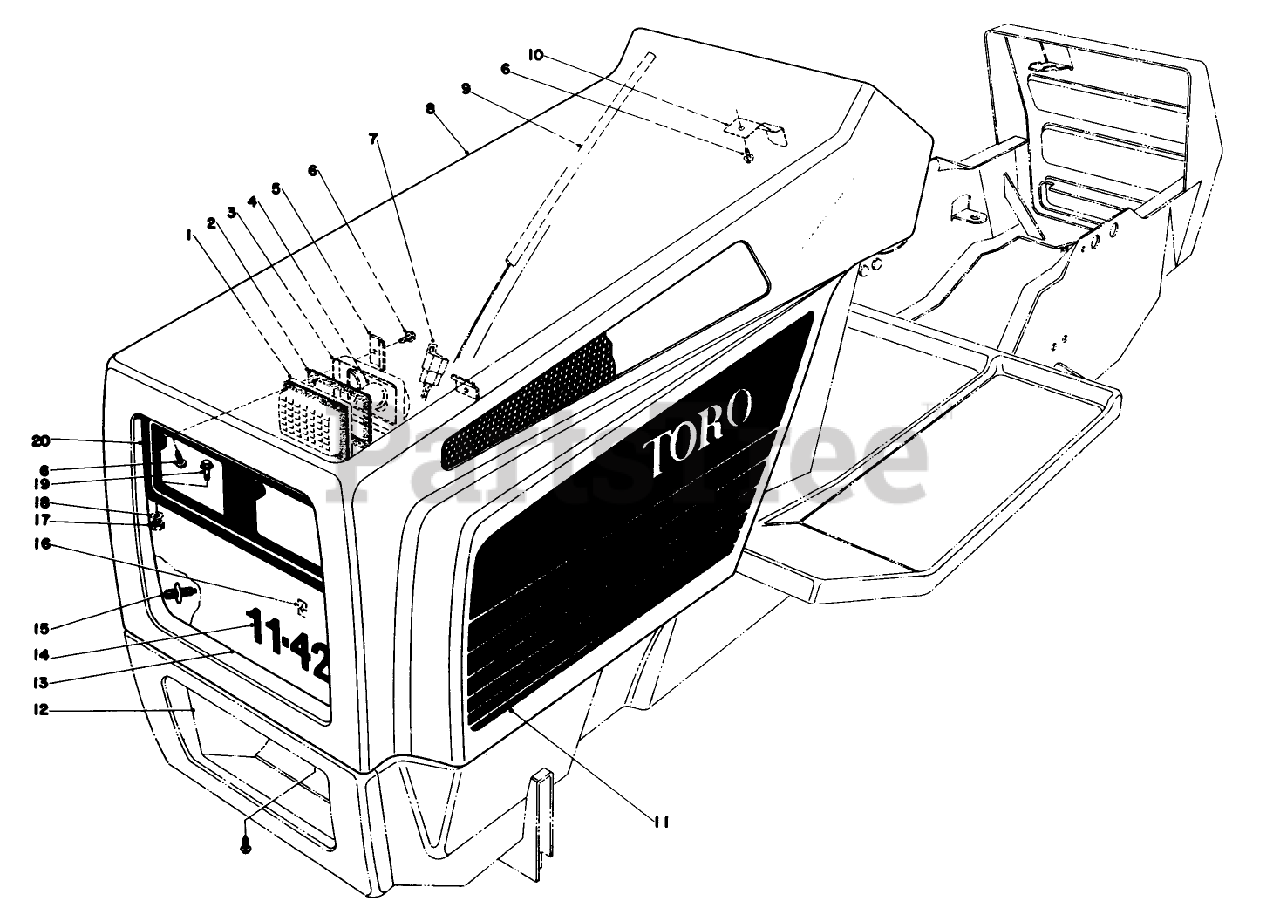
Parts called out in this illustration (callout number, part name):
1	14 Lens
3	Lamp-Green
6	Screw
10	SPRING LATCH
11	Decal Hood LH.
12	LOWER GRILLE
17	NUT-LOCK, SIDE
18	WASHER-FLAT
19	SCREW-SHWH
